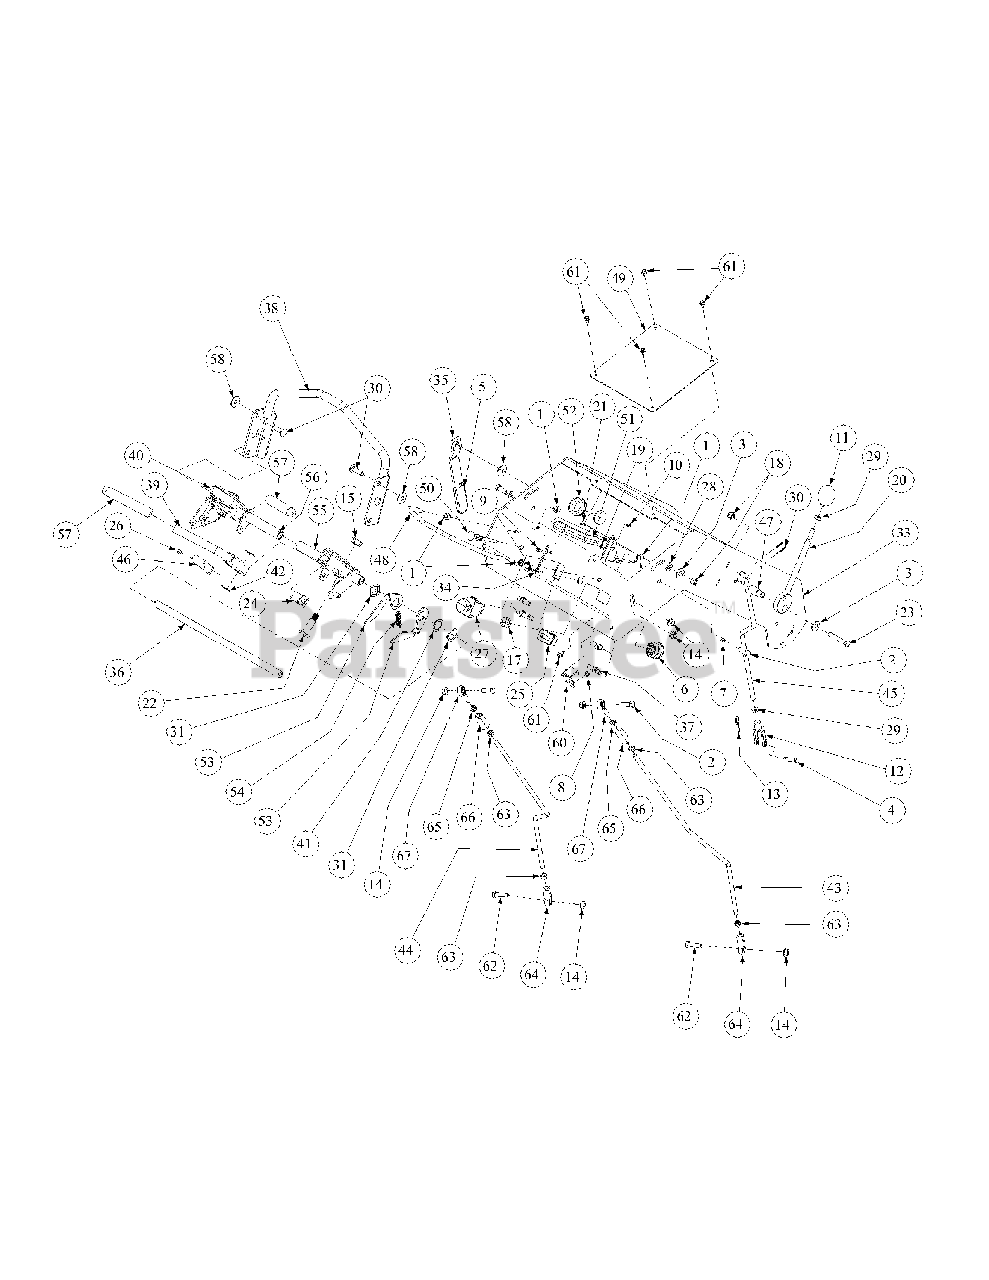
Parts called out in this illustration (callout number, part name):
1	Nut, 3/8-16
2	Hex Cap Screw, 3/8-16 x 1.0
3	Washer, 3/8 Zinc
4	Clevis Pin, 3/8 x 1-1/8
5	Yellow Grip, .250 x 1 x 3.50
6	Ignition Switch
7	Lock Washer, 3/8 Zinc
8	Nut, 1/4-20, Nylon Insert
9	Screw, 10-32 x 1/2
10	Nut, 10-32, Nylon Insert
11	Shifter Knob
12	Female Yoke
13	Hair Pin, 3/8-1/2
14	Nut, 3/8-16, Hex Flange Lock
15	Nut, 1/2-20, Center Lock
16	Screw, 3/8-16 x 1.25
17	Nut, 5/8-32
18	Nylock Nut, 3/8-16
19	Star Washer, 8-32
20	Brake Lever Assembly
21	Machine Screw, 8-32 x 0.375
22	Shoulder Screw, 58 x 1.48, 1/2-20
23	Hex Cap Screw, 3/8-16 x 2.25
24	Safety Switch, Normally Closed
25	Hour Meter
26	Screw, 10-24 x .500
27	Electric PTO Switch
28	Nylon Washer, 3/8
29	Nut, 3/8-16, Jam
30	Cotter Pin, .072 x 1.12 Long
31	Wave Washer, 1.38 OD x .88 ID x .029
32	Hour Meter Harness
33	Handle Weldment
34	Washer, 3/16 Zinc
35	Handle Lever Weldment
36	Upper Control Rod
37	Adjustable Center Stud, 3/8
38	Bar Cruz Weldment
39	Right Hand Handle Control Weldment
40	Left Hand Handle Control Weldment
41	Spacer, .91 x 1.250 x .100
42	Wave Washer, .688 ID x 1.16 OD
43	Long Connector Rod, Right
44	Long Connector Rod, Left
45	Long Brake Rod
46	Spring Retainer
47	Brake Lever Spacer
48	Handle Mount
49	Cover Control PLate
50	Choke Cable
51	Throttle Cable
52	Rubber Grommet, 1.0 ID x 1.75 OD x .125
53	Retainer Arm
54	Extension Spring, .057 Dia x .477 OD
55	Right Hand Pivot Control Handle Assembly
56	Left Hand Pivot Control Handle Assembly
57	Grip, .75 ID
58	Bell Washer, .396 x 1.14 x .095
61	Screw, 1/4-20
62	Hex Cap Screw, 3/8-16 x 1.25
63	Jam Nut, 3/8-24
64	B/Joint, 3/8-24, Right Hand Female
65	Jam Nut, 3/8-24, LH Thread
66	Turnbuckle
67	B/Joint, 3/8-24, Left Hand Female
